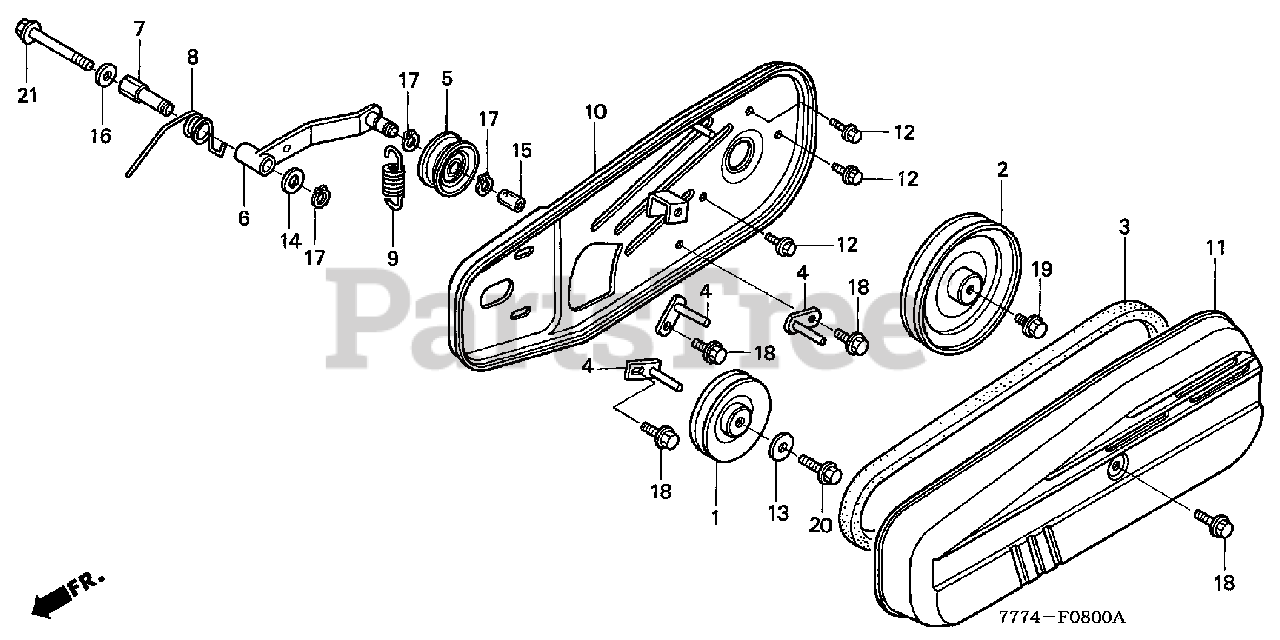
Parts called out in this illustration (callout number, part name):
1	PULLEY, DRIVE
2	PULLEY, DRIVEN (130MM)
3	V-BELT (SB-38)
4	STOPPER A, BELT
5	ROLLER, TENSIONER
6	ARM, TENSIONER
7	SHAFT, TENSIONER ARM
8	SPRING, TENSIONER ARM RETURN
9	SPRING, BELT TENSIONER
10	COVER, BELT (INNER) *R8* (BRIGHT RED)
10	COVER, BELT (INNER) *R280* (POWER RED)
11	COVER, BELT *R280* (POWER RED)
12	BOLT, FLANGE (6X14) (CT200)
13	WASHER (8MM)
14	WASHER (12.5MM)
15	TUBE, VINYL (10MM)
16	WASHER, PLAIN (10MM)
17	CIRCLIP, OUTER (12MM)
18	BOLT, FLANGE (8X16)
19	BOLT, FLANGE (8X18)
20	BOLT, FLANGE (8X25)
21	BOLT, FLANGE (10X75)
